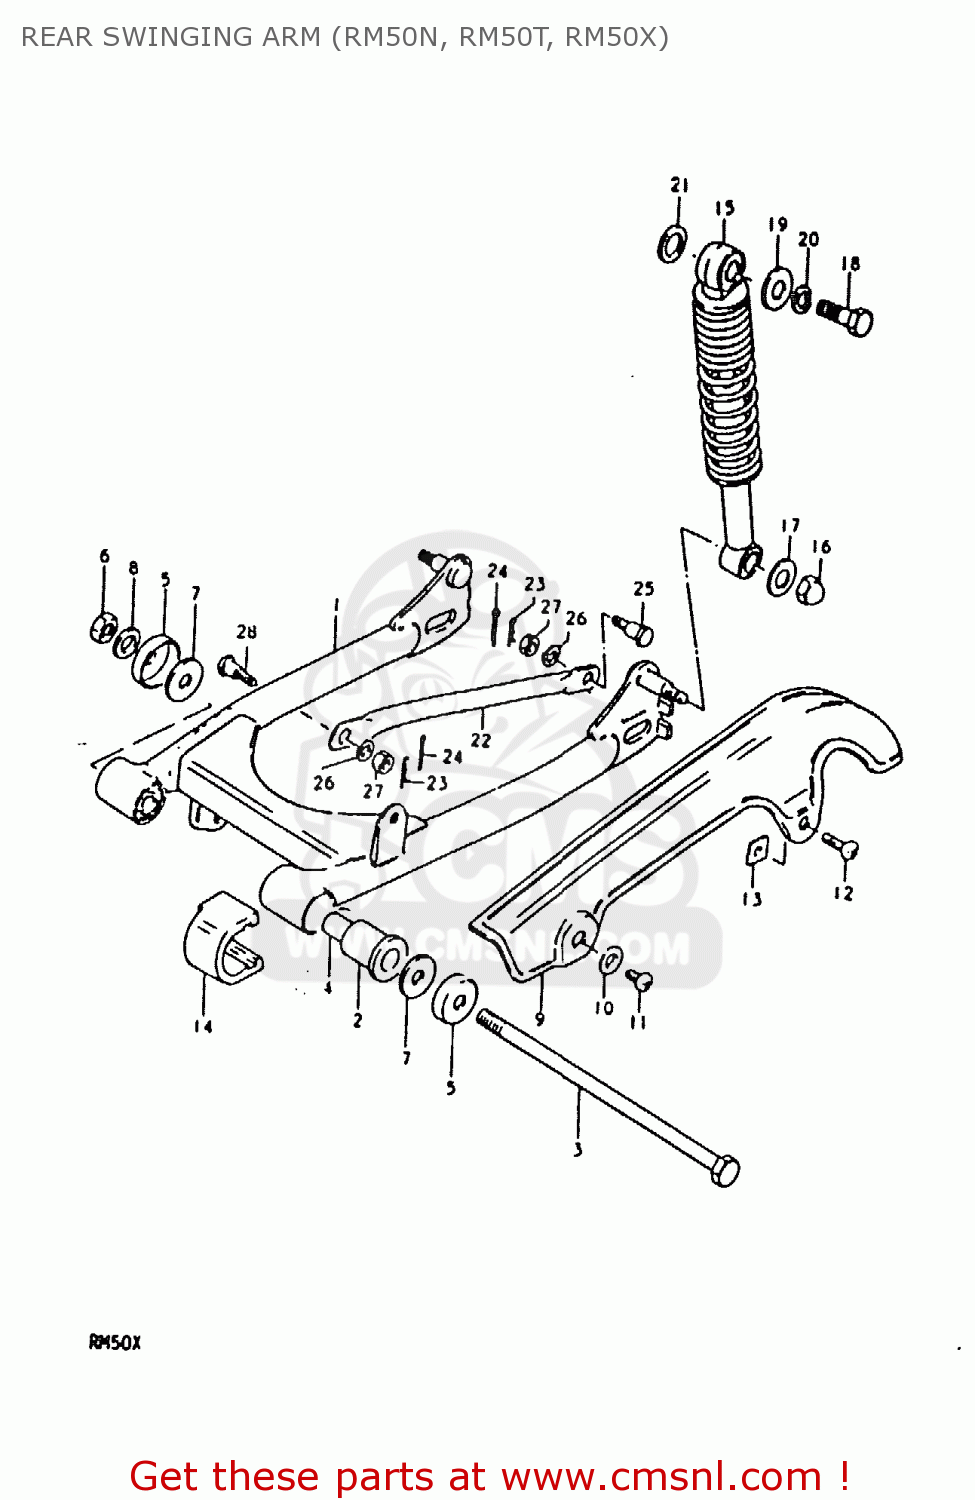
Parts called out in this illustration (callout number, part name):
1	SWING ARM ASSEMBLY,REAR
2	BUSHING
3	SHAFT, PIVOT
4	SPACER,RR SWGARM PIVOT
5	COVER,REAR SWING ARM DUST
6	NUT
7	WASHER (10.2X28X1.5)
8	WASHER
9	CASE,CHAIN
10	WASHER
11	SCREW
12	SCREW 6X12
13	NUT,CHAIN CASE RR
14	BUFFER,CHAIN TOUCH DEFLECTOR
15	ABSORBER ASSEMBLY,REAR SHOCK
16	NUT, LOWER LH
17	WASHER
18	BOLT
19	WASHER (6.5X24X1.6)
20	LOCK WASHER
21	WASHER
22	TORQUE LINK,REAR
23	CLIP
24	COTTER PIN
25	BOLT(8X26.5)
26	LOCK WASHER
27	NUT
28	BOLT(8X22)
